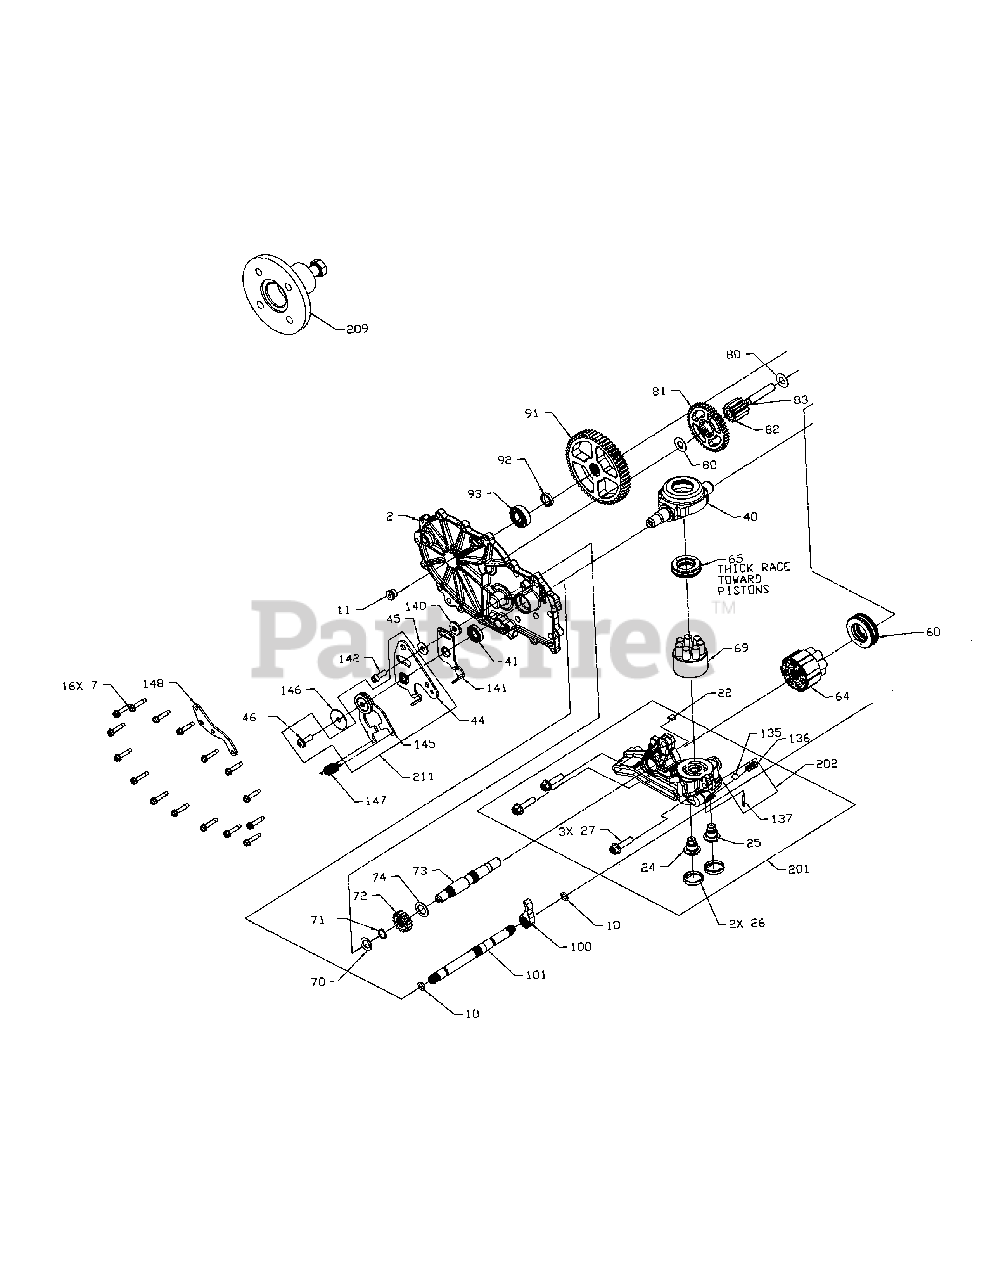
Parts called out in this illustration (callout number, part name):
1	Kit, Housing Main LH Chrg (includes
1	Housing, Main LH Chrg
1	Bushing .624 x .719 x .562
1	Brg, Jrnl .86 x .98 x .79
1	Pin .25 x .375
2	Kit, Cover Side LH Cntl (includes
2	Cover, Side LH Cntl
2	Bushing .624 x .719 x .562
2	Brg, Jrnl .86 x .98 x .79
7	HFHCS 1/4-20 x 1.25''
10	O-Ring 111.103 x .424
11	Plug 9/16/18 (Metal)
20	Center Section, LH Chrg
22	Plate, Bypass
23	Filter, Oil
24	Shock Valve
26	Seal, Plug 1.250 x .250
27	HFHCS 3/8-16 x 1.5 (Patch)
30	Seal, Lip .375 x .75 x .25
31	Ring, Ret .375 External
32	Rod, Bypass
33	Ring, Ret .750 Internal
34	Arm, Bypass
35	Ring, Rtng .375 Ext
40	Trunnion, Swashplate
41	Seal, Lip 18 x 32 x 7
44	Arm, Control
45	Washer .34 x .88 x .06
46	TWHCS 5/16-24 x 1.00 (Patch)
52	Shaft, Input
53	Brg, Ball 17 x 40 x 12 Open 6203
54	Ring, Ret Wire .561 ID
55	Washer 1.23 x 1.56 x .04
56	Seal, Lip 17 x 40 x 7
57	Ring, Ret 2.06 Internal
60	Bearing, Thrust
64	Cylinder Block Assembly 16cc
65	Bearing, Thrust Ball 30 x 52 x 13
69	Block 7 Piston Assembly
70	Washer .63 x 1.0 x .05
71	Ring, Ret 62 External
72	Gear, 16T
73	Shaft, Motor
74	Washer .72 x 1.16 x .04
80	Washer .5 x 1.0 x .03
81	Gear, 43T
82	Gear, 11T
83	Jack Shaft (Pin)
90	Ring, Ret 2.06 Internal
91	Gear, 54T
92	Spacer, .750 x 1.000 x .257
93	Bearing Ball .75 x 40 x 12
94	Shaft, Axle
95	Bearing Ball 1.0 x 52 x 15 Open 6205M
96	Seal, Lip TC4
97	Hub, 4 Stud (3.56 Taper)
99	Nut, Hex Lock 3/4-16
100	Pawl, Brake
101	Shaft, Brake
102	Handle, Brake
103	Clip, Retaining
105	HFHCS 1/4-20 x .75
106	Guard, Filter - LH
109	Spacer, .91 x 1.02 x .625
111	Fitting, Str 9/16-18 SAE .5 Barb
120	Fan, 7'', 10 Blade
121	Pulley 4.5 Inch
122	Nut, Hex Lock 1/2-20 Nylon
123	HFHCS 1/4-20 x .75
130	Tube, Connecting
131	Gerotor Assembly (1.6 cc/rev)
132	O-Ring, -137, 0.103 x 2.050
133	Cover, Charge Pump
134	HFHCS 1/4-20 x .75
135	Ball, Steel 7/16''
136	Spring relief .42 x .250
137	Pin, Spring .125 x .875
140	Spacer, .320 x 1.005 x .179
141	Arm, Neutral Left
142	SHCS 5/16-24 x 1 (Patch)
145	Assembly, RTN
146	Washer, .343 x 1.500 x .062
147	Spring, Extension .57 x 2''
148	Bracket Damper
200	Kit, Seal
201	Kit, Center Section, LH Chrg
202	Kit, Chrg Relief
203	Kit, Charge
206	Kit, Hub 4 Bolt
207	Kit, Fan/ Pulley
209	Hub Puller, 4 Bolt
210	Kit, Input Shaft
211	Kit, RTN Bidirectional LH
212	Kit, Axle Shaft
